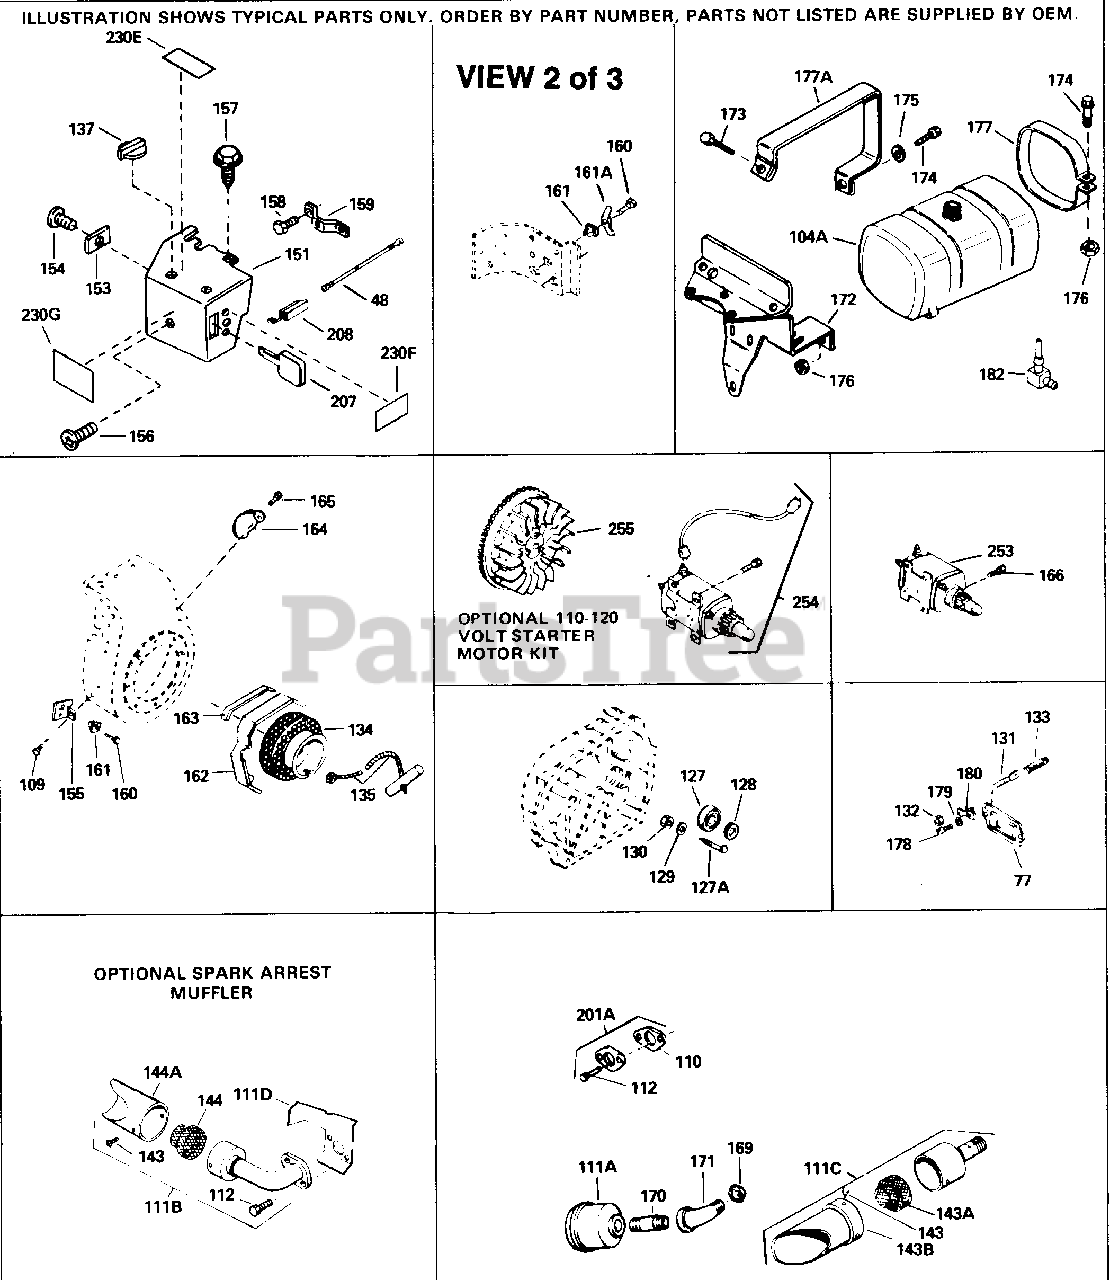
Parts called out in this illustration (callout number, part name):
15A	Governor Yoke
15B	Screw, 6-40 x 5/16"
48	Valve Lifter
110	Ground Wire
125	Exhaust Valve (Std.)(Incl. 151)
125	Exhaust Valve (1/32" OS) (Incl. 151)
126	Intake Valve (Std.) (Incl. 151)
126	Intake Valve (1/32" OS) (Incl. 151)
128	Belleville Washer
130	Screw, 5/16-18 x 2-1/2"
135	Resistor Spark Plug - RJ17LM
150	Valve Spring
151	Valve Spring Keeper
169	* Valve Cover Gasket
170	Breather Body
171	Breather Element
172	Valve Cover
173	Breather Tube
173A	Breather Tube Grommet
174	Screw, 10-24 x 1/2"
175	Lock Washer
176	Lock Nut, 10-24
182	Screw, 1/4-20 x 27/32"
184	* Carburetor To Intake Pipe Gasket
186	Governor Link
200	Control Bracket (Incl. 19, 203 & 204)
203	Compression Spring
207	Throttle Link
224	* Intake Pipe Gasket
227	Air Cleaner Elbow (Machined)
228	Stud, 1/4-20 x 6.20"
229	Nut & Lock Washer, 1/4-20
235	Air Cleaner Elbow Fitting
238	Screw, 10-32 x 7/8"
239	* Air Cleaner Gasket
239A	* Air Cleaner Gasket
245A	Air Filter
260	Blower Housing
262	Screw, T-40, 5/16-24 x 21/32"
265	Cylinder Head Cover
272	Screw, 5/16-18 x 3/4"
273	Carburetor Flange
275	Muffler
285	Starter Cup
286	Starter Screen
287	Screw, 1/4-28 x 7/16"
291	Fuel Line
292	Fuel Line Clamp
298	Screw, 1/4-15 x 3/4"
299	"U" Type Nut
300	Fuel Tank (Incl. 292 & 301)
301	Fuel Cap (Red)
305	"O" Ring
305	Oil Fill Tube
308	Fill Tube Clip
310	Oil Fill Plug
325	Wire Clip
340	Fuel Tank Bracket
341	Fuel Tank Bracket
342	Screw, 1/4-20 x 5/8"
366	Muffler Elbow
366A	Muffler Nipple
367	Lock Nut
370	Instruction Decal
370A	Logo Decal
370B	Instruction Decal
380	Carburetor (Incl. 184)
390	Rewind Starter
400	* Gasket Set (Incl. items marked PK in notes) Incl. part #'s 27272 (2), 2789 6 (2), 27913 (1), 27915 (2), 27930 (1 ), 28938B (1), 29673 (1), 30684 (1), 31688 (1), 33355 (1)
420	SAE 30 4-Cycle Engine Oil (Quart)
453	Engine Mounting Base
454	Screw, 5/16-18 x 3/4"
